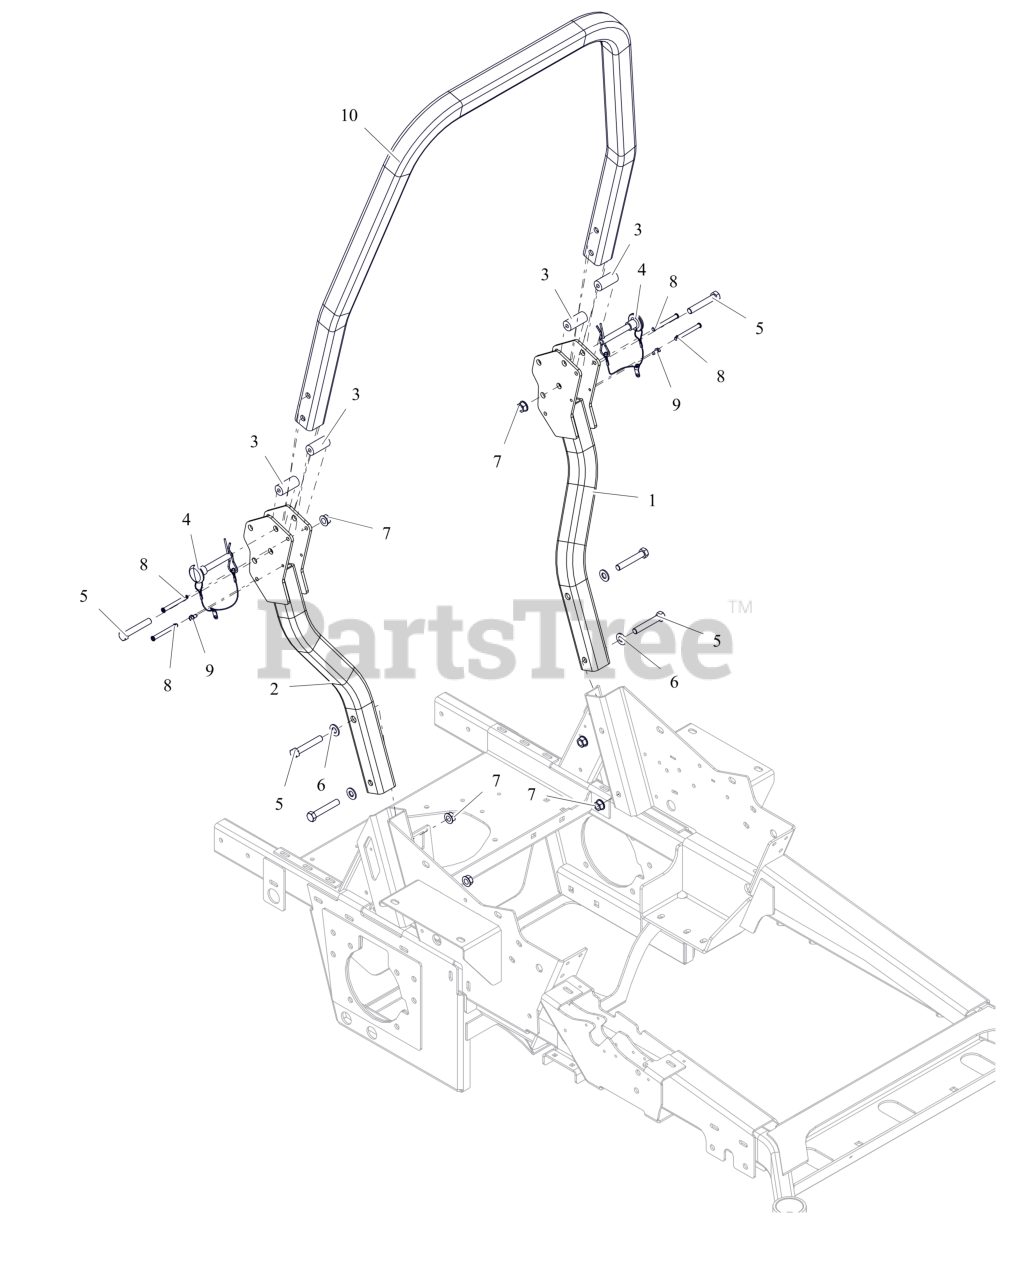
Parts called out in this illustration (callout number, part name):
1	WLDMT, LH ROPS MOUNTING W/ SAFETY DECAL
2	WLDMT, RH ROPS POST W/ SAFETY DECAL
3	BUMPER, ROPS ANTI-VIBRATION
4	PIN, ROPS W/LANYARD
5	BLT, HEX .50-13X3.00 G5 ZCC
6	WSHR,FLT .531X1.062X.095 ZCC
7	NUT-LK-CTR-FLG .500-13 GG ZCC
8	PIN, SLIC .312 X 2.570
9	SCR-TAP .25-20X.50 HWH ZCC
10	HOOP, ROPS
